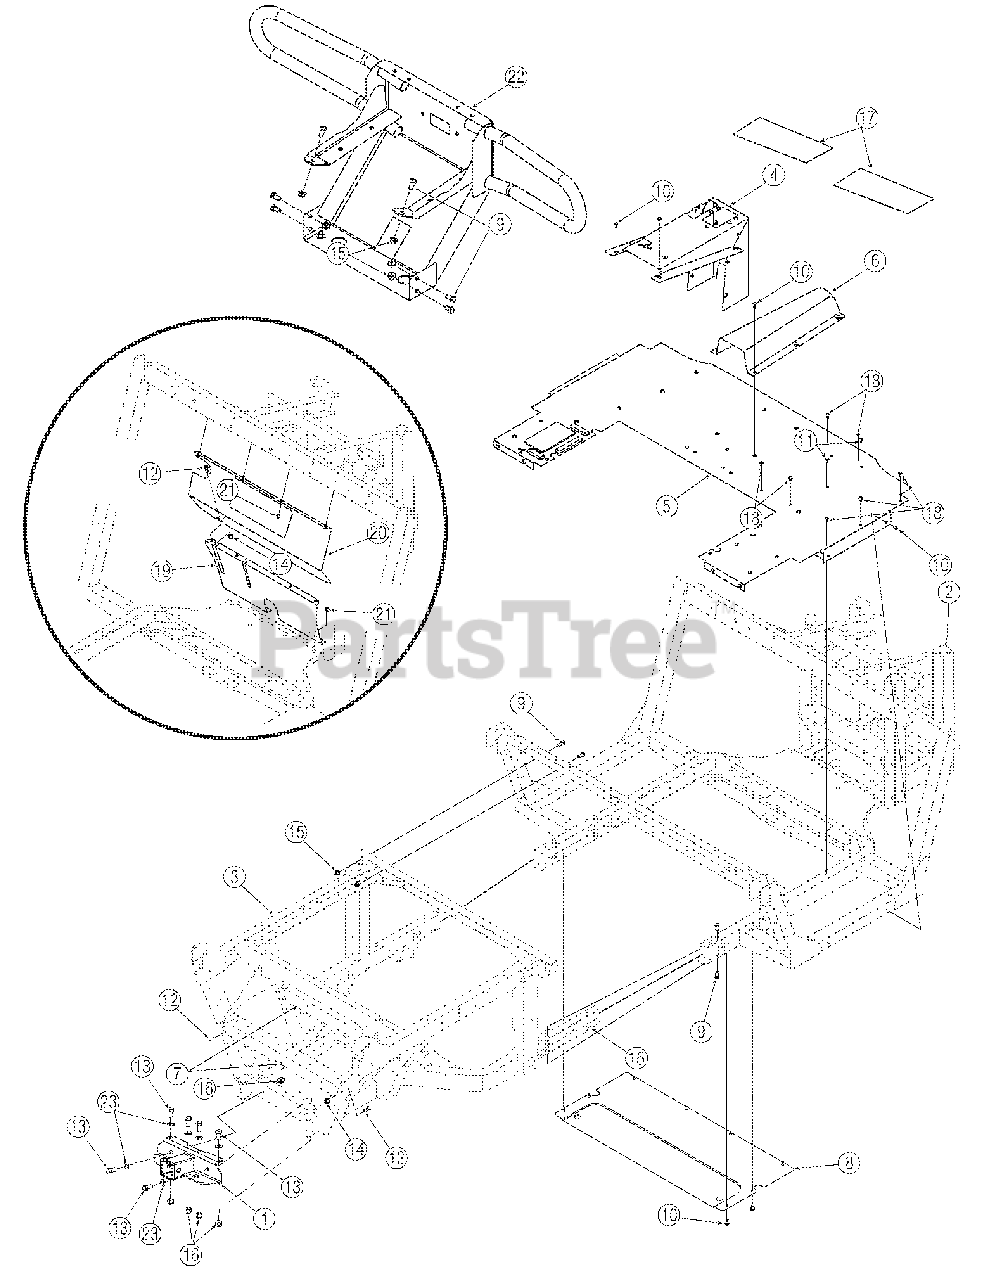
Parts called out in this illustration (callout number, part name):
1	Hitch Assembly, receiver Rr
2	Frm Assembly, front, uv
10	Scr, tt, 5/16-18, 0.500,
11	Scr, ab, 1/4-14, 0.625, trustrxi
12	Screw, 5/16-18, .75, gr5, std
13	Screw, 1/2-13, 1.00, gr5, std
14	Nut, flglk, 5/16-18, grf, nylon
15	Nut, flglk, 3/8-16, grf, nylon
16	Nut, hexlk, 1/2-13, grb, nylon
17	Pad, abrasive, toe Plate
18	Clip, pnl, ret,
21	Scr, tt, 1/4-20 x .500
23	Washer, Flat, .51 x 1.0 x
